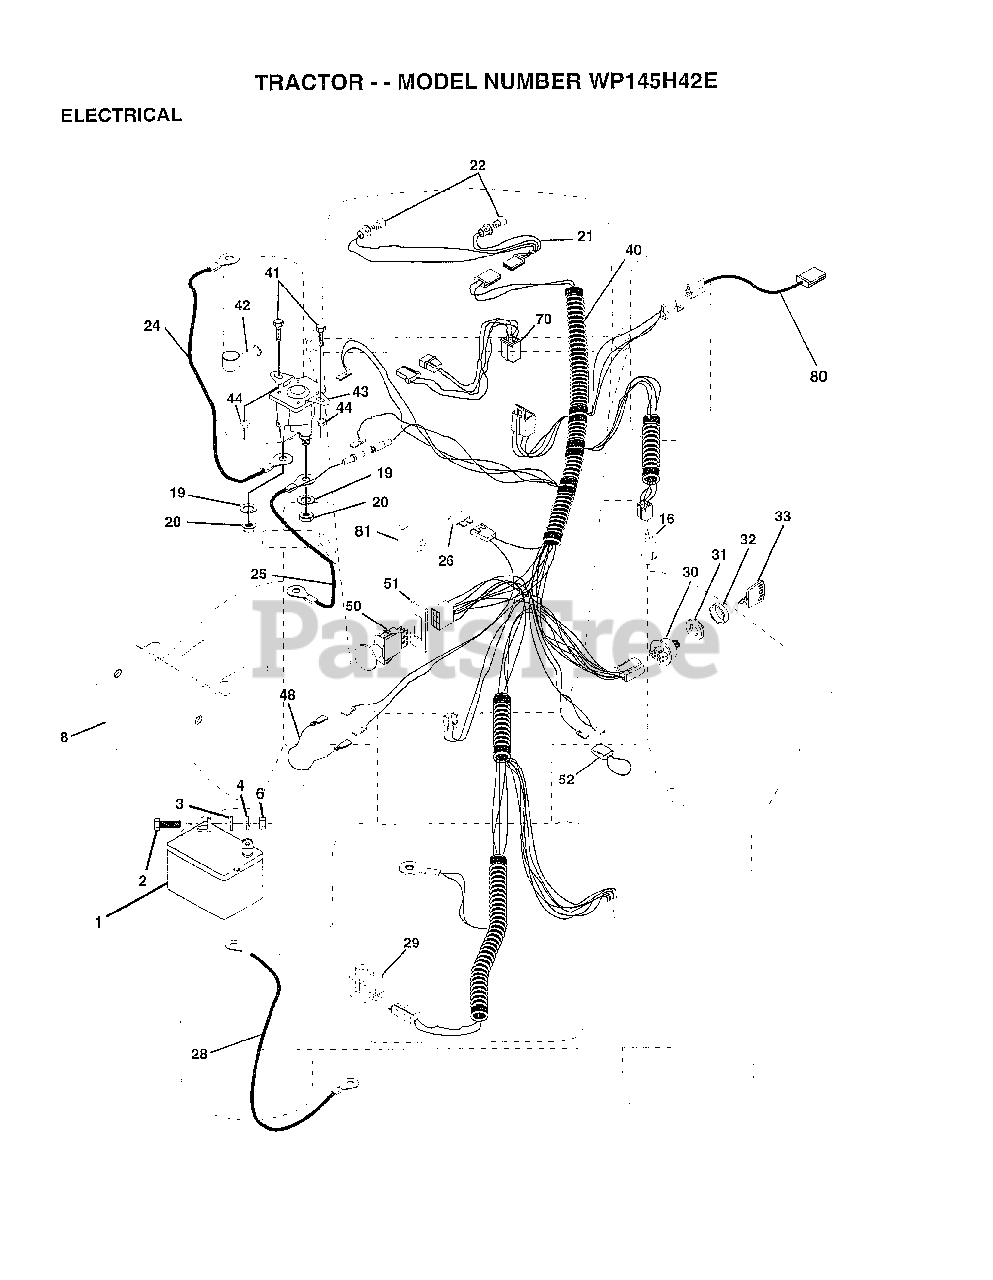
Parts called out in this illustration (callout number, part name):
3	WASHER
4	LOCKWASHER
8	"CASE,BATTERY.MECH"
16	SWITCH INTERLOCK
20	NUT
21	HARNESS.ASM.HDLIG
22	HEADLAMP BULB
24	CABLE.BTRY.6GA.RD
25	CABLE.BTRY.6GA.38
26	FUSE HYT
28	CABLE T
29	SWITCH.PLUNGER
30	SWITCH IGN 4POS
31	NUT IGNITION
32	COVER KEY SWITCH
33	KEY
40	IGNITION HARNESS
41	BOLT HXHD FIN
44	NUT HXKEP 1/4X20
48	ADAPTER AMMETER
50	PTO SWITCH.BLK
51	RING RETAIN PTO
52	PROTECTION LOOP
70	HARNESS.ENG.DUAL
80	HARNESS.CLUT.EVX.
81	RELAY ASSY T
